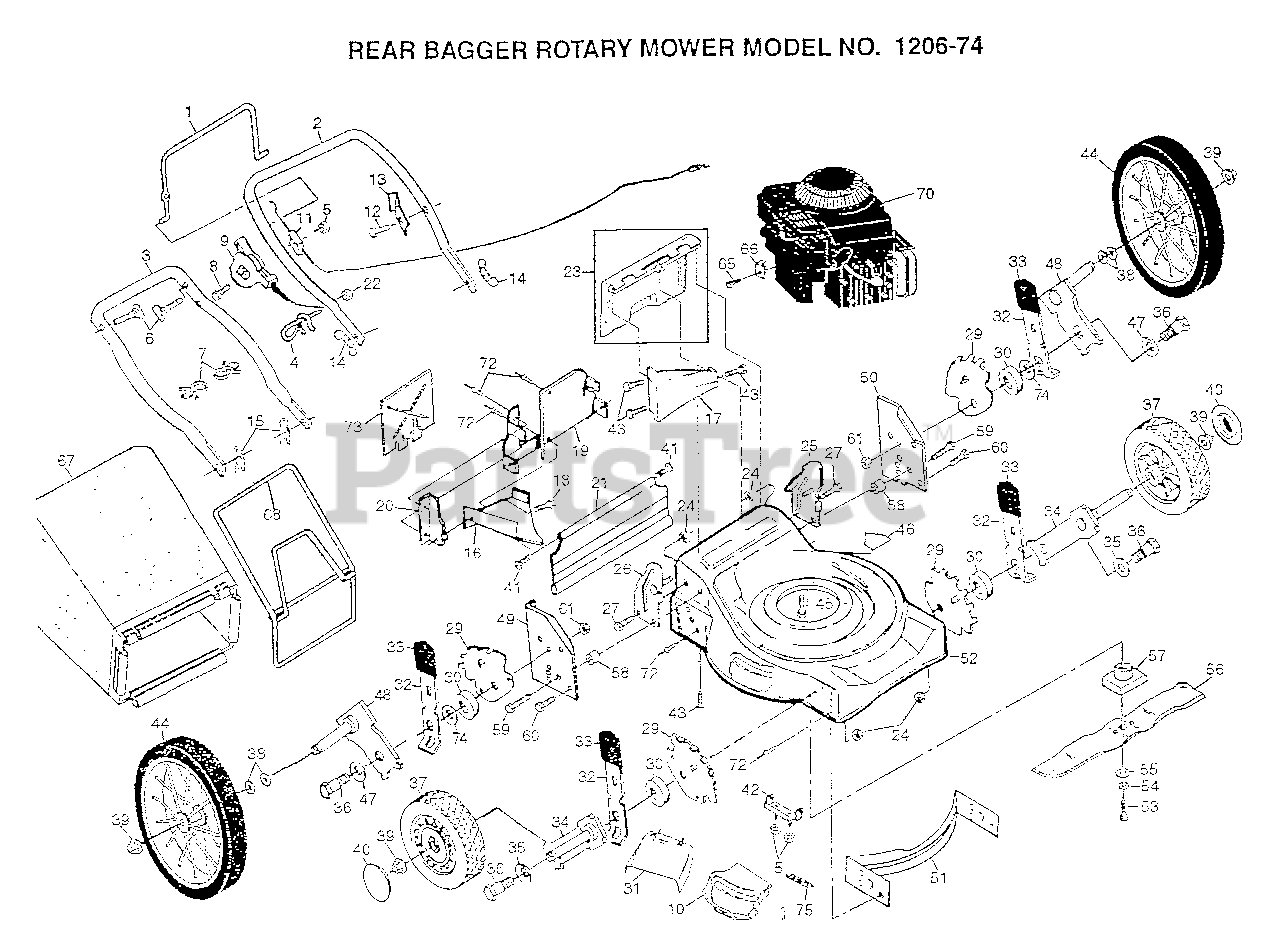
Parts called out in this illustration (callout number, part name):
1	CONTROL BAR
3	HANDLE.LWR.DLX.20
4	ROPE GUIDE
6	BOLT.HANDLE.LM
8	SCREW.HXHD.WASH.
9	"CONTROL, THROTTLE"
10	DOOR.MULCH.COMBI
11	"CABLE,ENG ZONE CO"
12	TAPPING SCREW
13	"BRKT,UPSTOP"
14	"NUT,WING PM"
15	HAIRPIN COTTER
16	DISCHARGE GUARD
18	SCREW.HXTAP.10-24
19	PLATE.BACK.20RD
21	SKIRT.PUSH.20RD
23	KIT.DOOR.RR.20STL
24	LOCKNUT PM
25	BRACKET.HDLE.LH.
26	BRACKET.HDLE.RH.
27	SCREW.HXWS.5/16
29	BRACKET.ADJ.9POS.
30	SPACER.HEIGHT.ADJ
31	GUARD.DISCH.CLIPO
32	SPRING SELECTOR
33	KNOB PM
34	ARM.AXLE.ASM.BZP.
35	"WASHER, BELLEVIL."
36	BOLT SHLD 3/8-16
37	WHEEL.8X2.RAD.GRY
38	WAVE WASHER
39	HEX FLANGE LOCKNT
40	HUB CAP
41	HINGE SCREW
42	BRACKET.HINGE.W/F
43	SCREW
44	WHEEL TIRE PM
45	BOLT.ENG.3/8-16
46	DECAL HYT
48	"AXLE ARM,REAR PM"
49	BRKT.SUPT.RH
50	BRACKET.SUPT.WHL.
52	HOUSING ASSY
53	SCREW
54	LOCKWASHER
55	"WASHER,HARDEN"
56	BLADE.20.MULCH.AY
57	BLADE ADAPTOR
58	SPACER.PM
59	SCREW.HX.WSHD.
61	LOCKNUT PM
65	SCREW PM
66	CABLE CLAMP
67	GRASSBAG.250B1
68	FRAME.CATCHER.2.5
71	ROD.HINGE.COMBI-C
72	BLIND RIVET
73	MULCHER PLATE
74	WASHER PM
75	SPRING.HINGE
